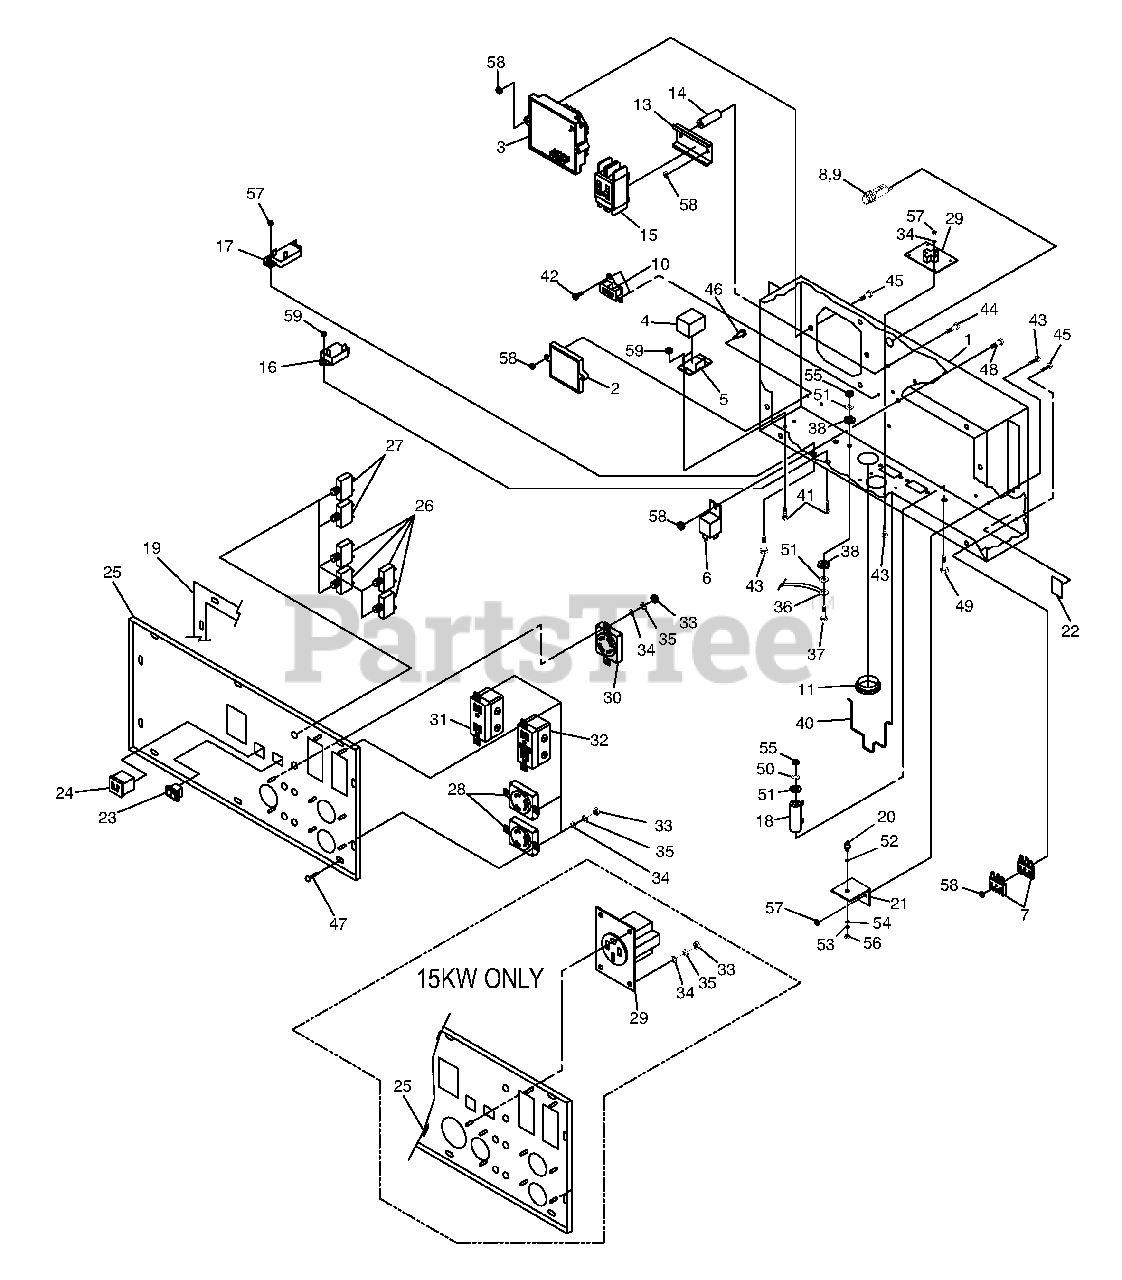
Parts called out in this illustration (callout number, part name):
1	CONTROL PANEL BOX (15 KW)
2	ELECTRONIC GOVERNOR / IDLE CONTROLLER
3	ASSY PCB VREG AIR COOLED
4	RELAY 3PDT 12VDC
5	RELAY BASE 3PDT 12VDC
6	RELAY PNL 12VDC SPST 30A
7	RECTIFIER-BATTERY CHARGER
8	HOLDER FUSE
9	FUSE 10A X AGC10
10	TRANSFORMER, IDLE CURRENT
11	BUSHING SNAP
13	DIN RAIL 59.5mm LONG
14	SPACER .25 X .50 X 2.5 (17.5 KW)
15	CIRCUIT BREAKER 50A 400V 2POLE
16	CIRCUIT BREAKER 10A 1POLE
17	CIRCUIT BREAKER 6A 1POLE
18	RESISTOR 25R 5% 25W
19	GASKET, PORTABLE CONTROL PANEL
20	RECTIFIER 1N1206R
21	HEATSINK
22	TAPE ELEC UL PERMACEL
23	SWITCH, ROCKER -/0
24	OUTLET, 12VDC SNAP
25	PANEL, SHEET METAL (15 KW)
26	CIRCUIT BREAKER 30A
27	CIRCUIT BREAKER 20A
28	OUTLET 30A 120V RECEPT
29	OUTLET 50A 125/250V
30	OUTLET 30A 125/250V
31	OUTLET 20A 120V DPLX
32	OUTLET 20A 120V GFCI
33	NUT HEX M4-0.7 (15 KW)
34	WASHER FLAT #8 (15 KW)
35	WASHER LOCK M4 (15 KW)
36	GROUND WIRE
37	SCREW HHC M6-1.0 X 35
38	WASHER LOCK SPECIAL 1/4"
40	SPRING RETAINER (17.5 KW)
41	SCREW PPHM M3-0.5 X 12
42	SCREW PPHM M3-0.5 X 8
43	SCREW PPHM M4-0.7 X 10
44	SCREW PPHM M5-0.8 X 80 (17.5 KW)
45	SCREW PPHM M5-0.8 X 30
46	SCREW HHC M5-0.8 X 25
47	SCREW HHTT M5-0.8 X 10
48	SCREW HHC M5-0.8 X 10
49	SCREW HHC M6-1.0 X 65
50	WASHER LOCK M6 (1/4")
51	WASHER FLAT 1/4"
52	WASHER MICA .203
53	WASHER FLAT #10
54	WASHER STEP NYLON .20
55	NUT HEX M6-1.0
56	NUT HEX #10-32
57	NUT HEX M4-0.5 NYINS
58	NUT HEX M5-0.8 NYINS
59	NUT HEX M3-0.5 NYINS
